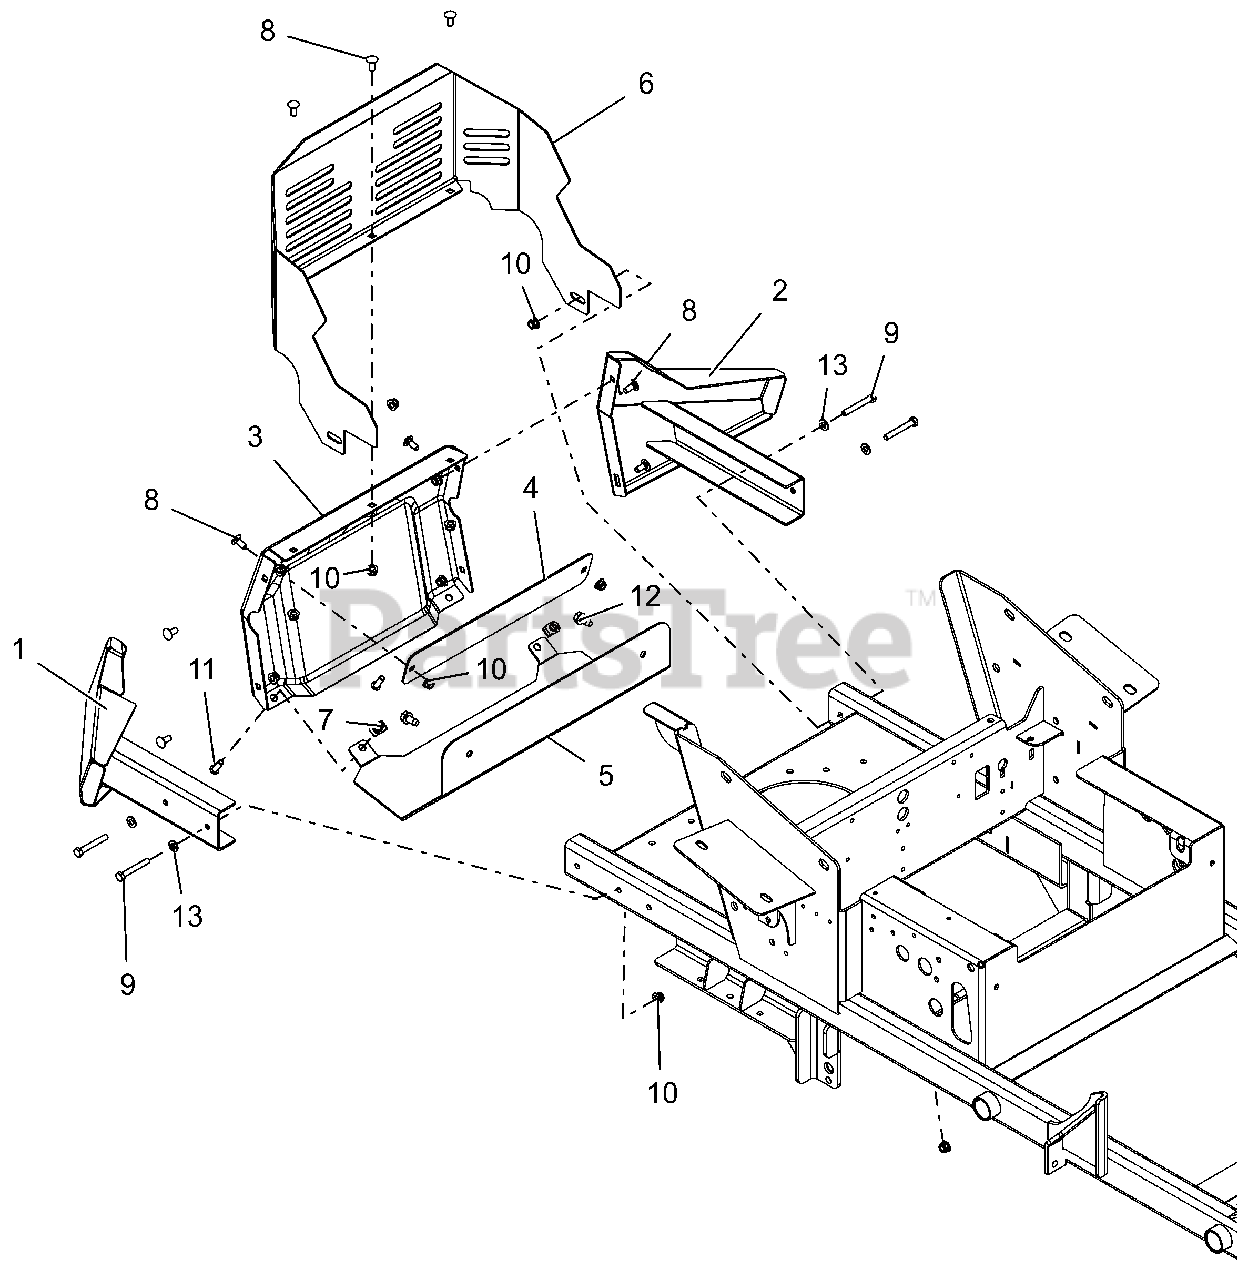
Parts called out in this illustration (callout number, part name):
1	RH RR BMPR WING W/SAFETY DECAL
2	LH RR BMPR WING W/SAFETY DECAL
3	PT200/400 REAR BUMPER - BLACK
4	BACKER PLATE - RED
5	PT100 MUFFLER GUARD -BLACK
6	GUARD, PT100 ENGINE
7	NUT-CLIP RETAINER 5/16-18X.56
8	@BLT-RDHDSQNK .31-18X.75 G5YZ
9	@BLT-HEX .31-18X2.25 GR5 YWZC
10	@NUT-LK-NYL-FLG .31-18 YWZC
11	SCR-SKH .31-18X1.0 BTNHD YWZC
12	@SCR-TAP .38-16X.75 HWH TR YWZ
13	@WSHR-FL-STL.344X.688X.065YWZC
